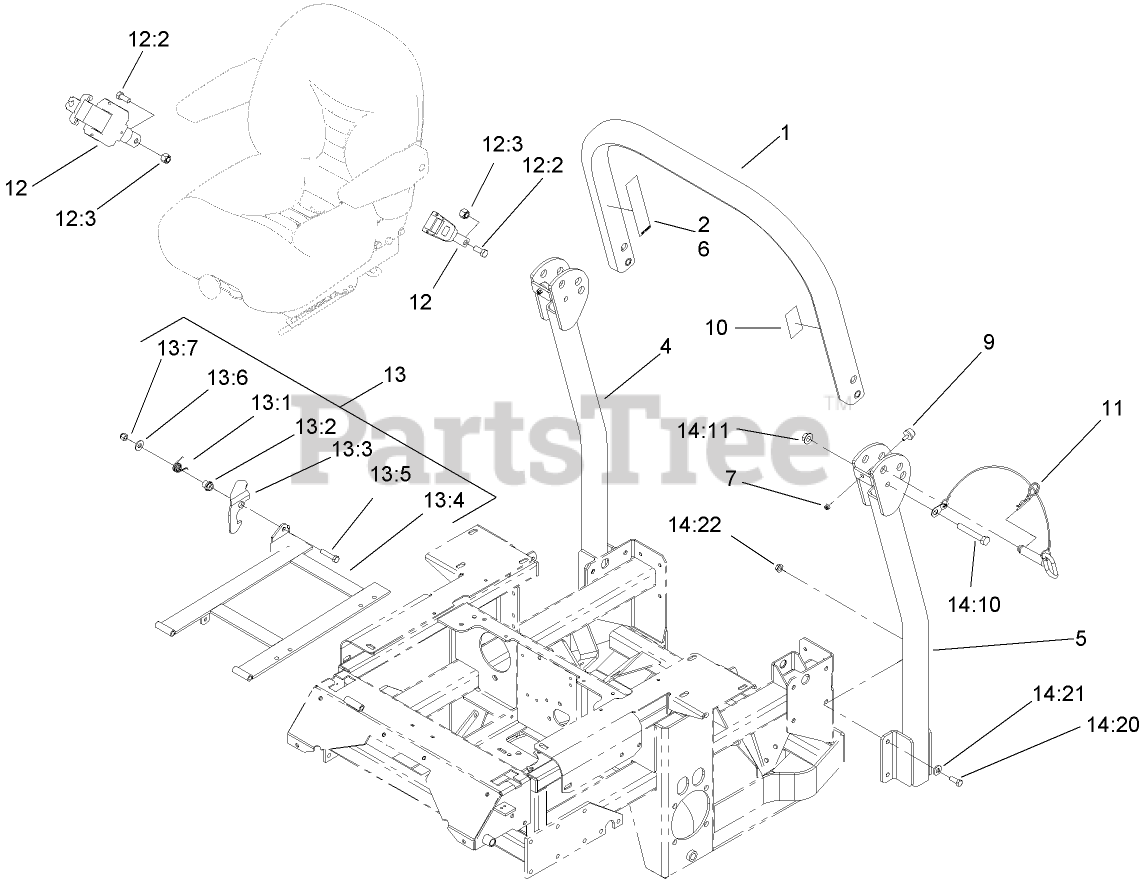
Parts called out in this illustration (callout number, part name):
1	Upper Tube ASM
2	DECAL-WARNING, FOLDING ROPS
4	TUBE-SUPPORT, RH
5	TUBE-SUPPORT, LH
6	DECAL-WARNING
7	NUT-LOCK, NI
9	BUMPER-RUBBER
10	DECAL-ROPS
11	PIN-FOLD, ROPS
12	RETRACTABLE SEATBELT KIT
12:2	SCREW-HH
12:3	NUT-LOCK
13	SEAT FRAME ASM
13:1	SPRING-TORSION, LATCH
13:2	BUSHING-LATCH, SEAT
13:3	CATCH-LATCH, SINGLE
13:4	SEAT FRAME ASM
13:5	SCREW-HH
13:6	WASHER-FLAT
13:7	NUT-LOCK, NI
14	BAG-BOLT
14:10	SCREW-HH
14:11	NUT-HF
14:20	SCREW-HH
14:21	WASHER-BELLEVILLE
14:22	NUT-HHF, WHIZ
